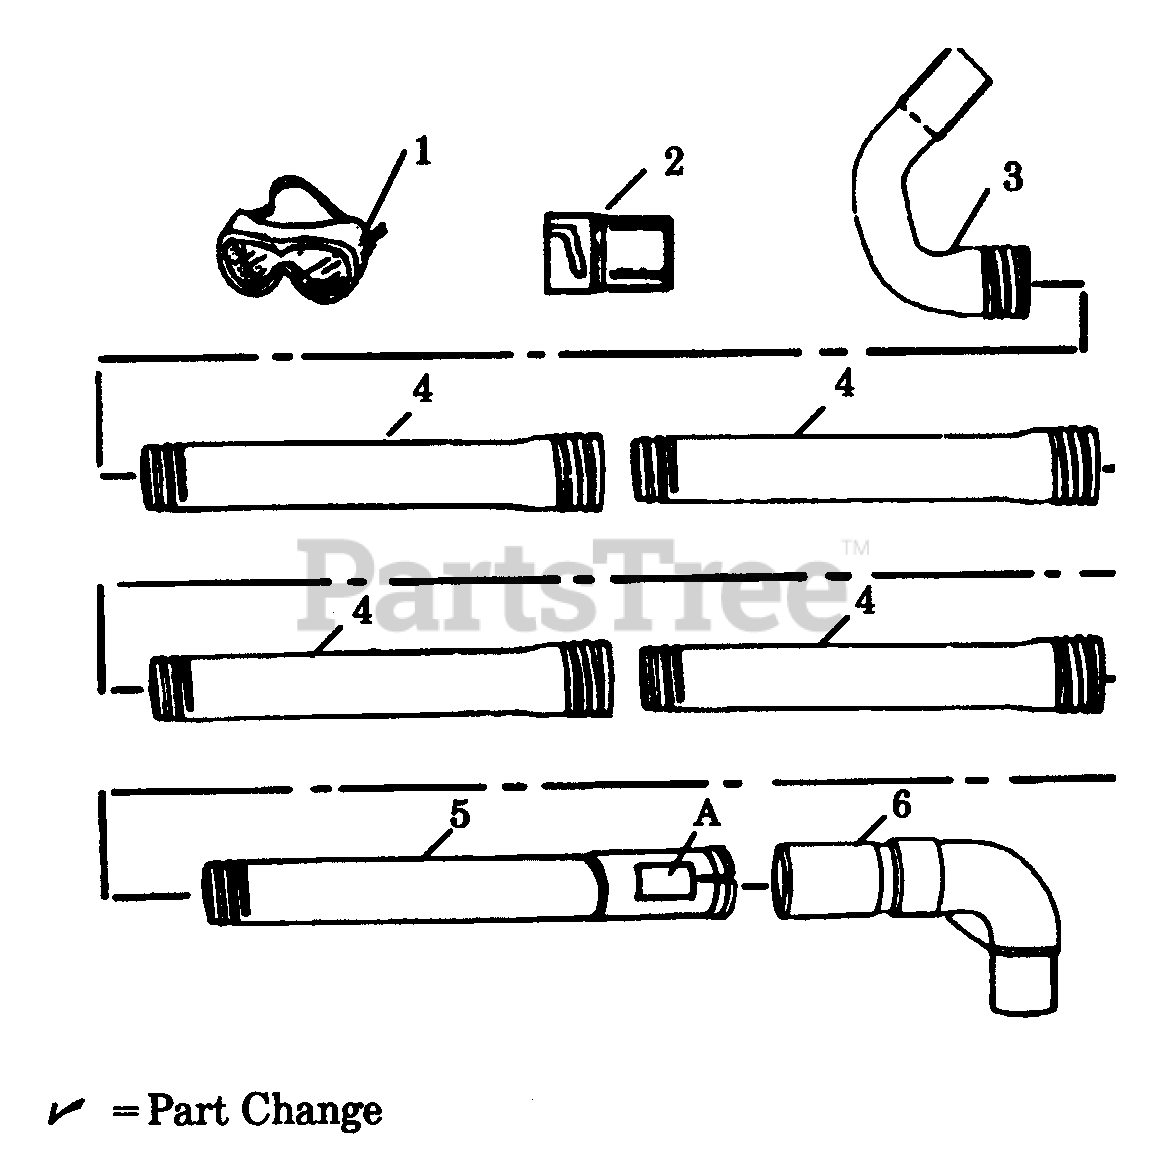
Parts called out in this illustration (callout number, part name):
4	Extension Tube
5	Pivot Tube
A	Warning Decal
